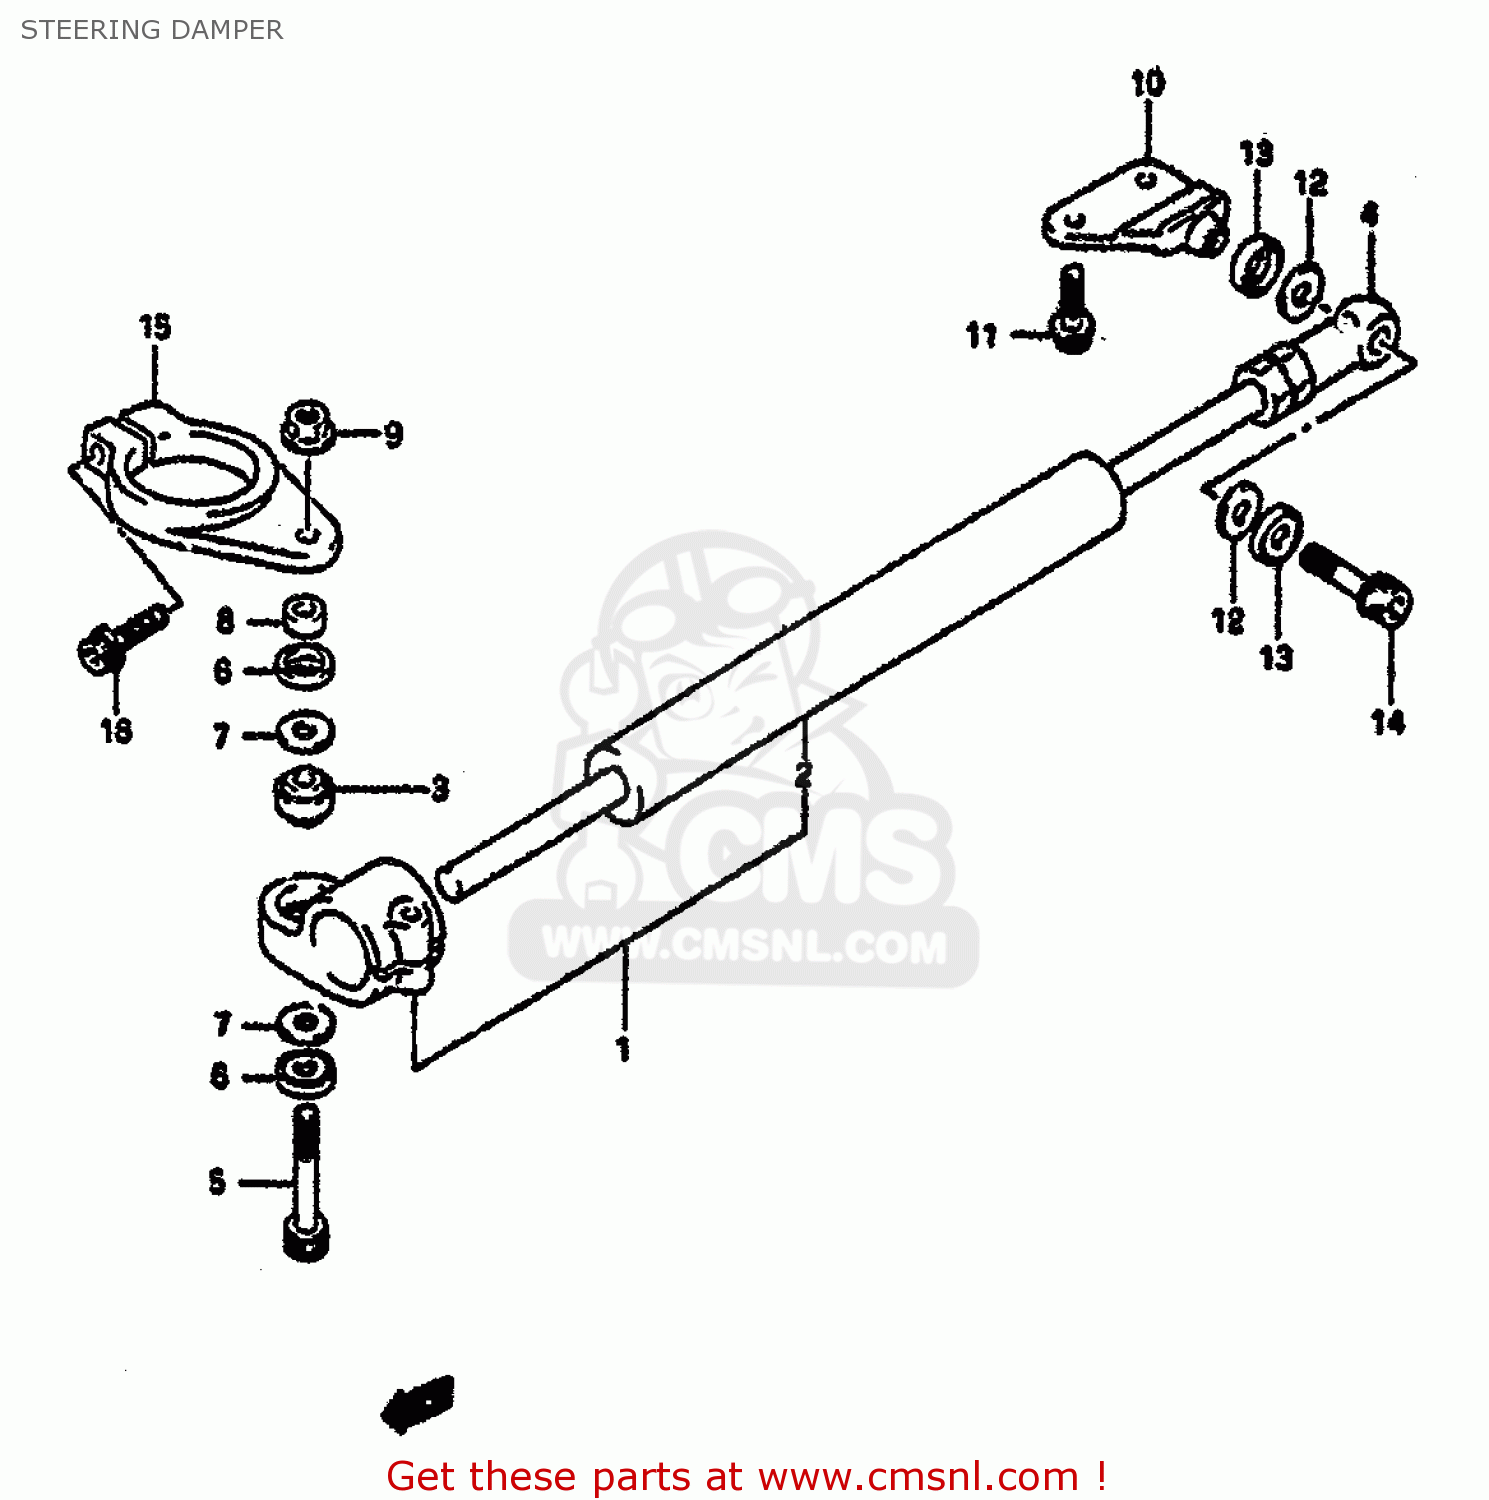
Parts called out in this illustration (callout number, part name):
1	DAMPER ASSEMBLY,STEERING
2	DAMPER,STEERING
3	BEARING(8X17.5X11)
4	PILLOW BALL,ROD END
5	BOLT
6	7
7	SHIM
8	SPACER (8.4X14X6)
9	NUT
10	BOSS,STEERING DAMPER
11	BOLT
12	SHIM
13	14
14	BOLT, FRONT RH
15	BRACKET,STEERING DAMPER
16	BOLT
